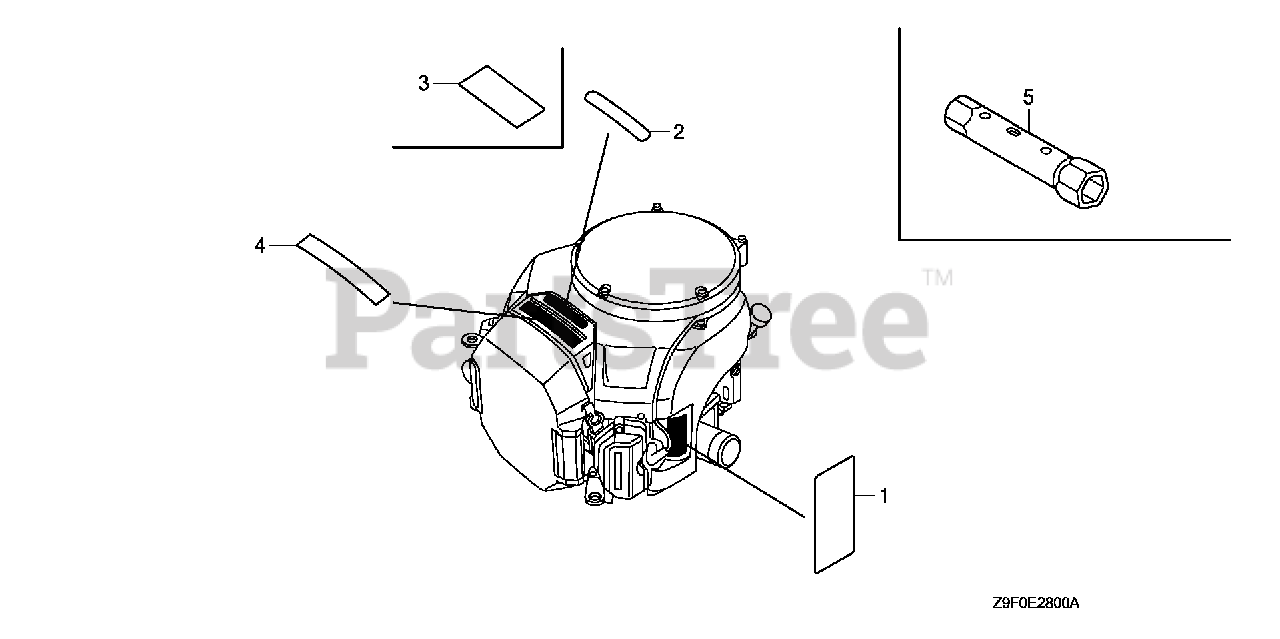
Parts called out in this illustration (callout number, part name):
1	MARK, OPERATOR CAUTION (ENGLISH)(MADE IN JAPAN)
2	EMBLEM (GXV630)
4	MARK, HONDA
